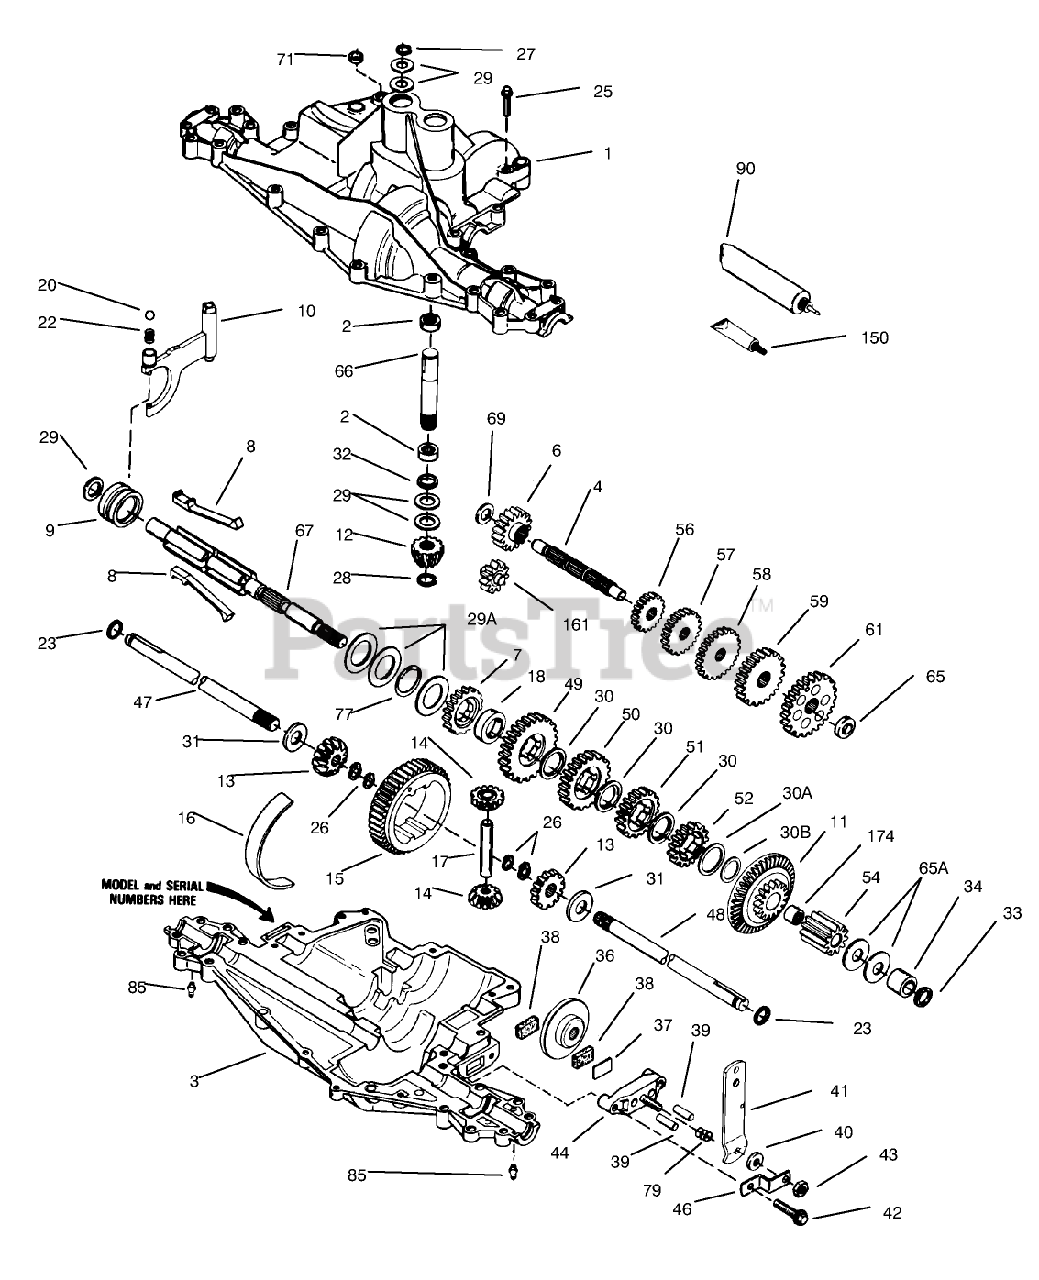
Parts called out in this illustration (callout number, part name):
1	Transaxle Cover
2	Bearing-Needle
3	Transaxle Case
4	Countershaft
6	Spur Gear (16 Teeth)
7	Gear-Spur (22 teeth)
8	Shift Key
9	Shift Collar
10	Shift Rod Fork
11	Bevel Gear Bearing (44/16 Teeth) (Incl. Ref. #174)
12	Bevel Pinion (14 Teeth)
13	Gear Bevel
14	Gear Pinion
15	Gear-Ring
16	Bearing Strip
17	Drive Pin
18	Neutral Spacer
20	Ball (3/8" dia.)
22	Spring
23	Ring-Seal
25	Ring Set (.020 O S)
26	Retaining Ring (pkg of 2)
27	Ring-Snap
28	Ring-Retainer
29	Washer
29A	Washer
30	Washer
30A	Washer
30B	Washer
31	Washer
32	O Ring
33	O-Ring
34	Bushing
36	Brake Disk
37	Brake Pad Plate
38	Brake Pad
39	Dowel Pin
40	Washer
41	Brake Lever
42	Ring Set (.020 O S)
43	Locknut
44	Nozzle-Carburetor
46	Bracket
47	Axle (16-3/4" Ig.)
48	Axle (11-9/16" Lg.) (Incl. Ref. #26)
49	Gear-Spur, 30 Teeth
50	Gear-Spur, 25 Teeth
51	Gear-Spur (22 teeth)
52	Gear Spur 19t
54	Spur Gear (11 Teeth)
56	Gear-Spur, 20 Teeth
57	Gear-Spur, 25 Teeth
58	Gear-Spur (28 teeth)
59	Gear-Spur (30 teeth)
61	Spur Gear (34Teeth)
65	Washer
65A	Washer
66	Input Shaft (3.522" Ig.)
67	Shifter Brake Shaft
69	Thrust Washer
71	Cut Seal-Square
77	Inverted Retaining Ring
79	Piston ASM (.020 O S)
90	Grease 32 Oz
150	Gasket Eliminator
161	Reverse Idler Assembly
174	Needle Bearing
